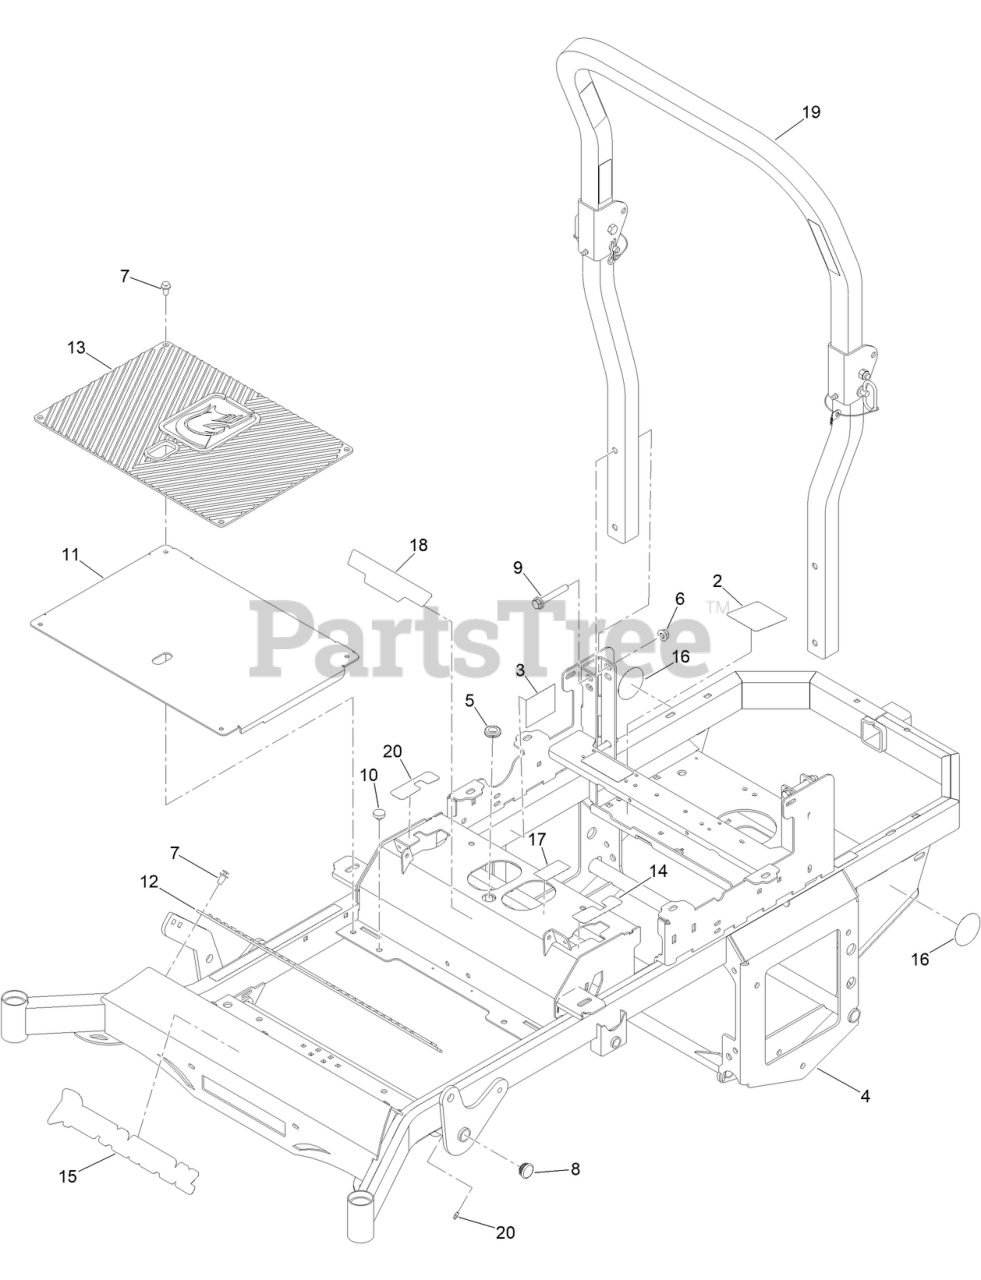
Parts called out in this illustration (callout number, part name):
2	DECAL-DECK BELT ROUTING
3	DECAL-E P A
4	FRAME ASM W/ DECALS
5	GROMMET-RUBBER
6	1/2-13 HEX STOVER LOCKNUT GR C ZINC
7	8MM PUSH TYPE RETAINER NYLON BLACK
8	1-1/4 IN ROUND TUBE PLUG
10	PUSH-IN RUBBER BUMPER MWR FLOOR
11	MWR FLOORBOARD PAINT
12	MWR RUBBER FOOT REST MAT
13	MWR LOGO FLOOR MAT
14	DECAL-MOTION CONTROL
15	DECAL-SPARTAN, FRONT
16	MWR PARKER PUMP DECAL
17	DECAL-WEIGHT, SEAT
18	2022 SRT-XDE W/GT TRAC DECAL
19	MWR FOLD DOWN ROPS
20	1/4 DRIVE TYPE STRAIGHT GREASE FITTNG ZC
